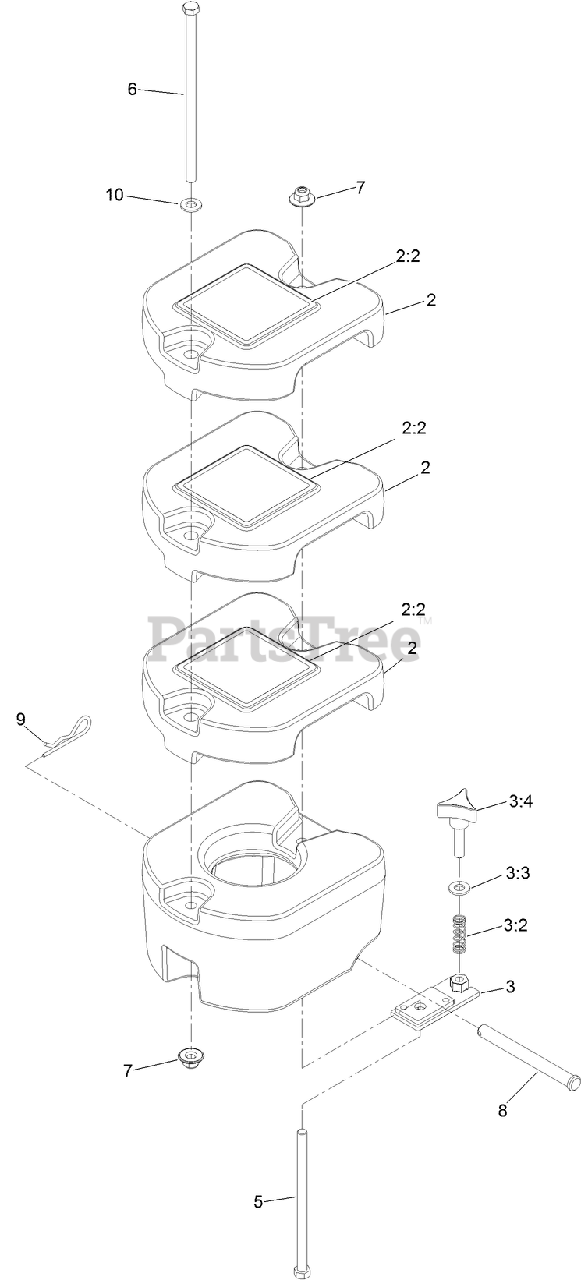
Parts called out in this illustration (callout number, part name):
2	WEIGHT-20LB
2:2	DECAL-WARNING, TRACTION
3	CASTER WEIGHT BRACKET ASM
3:2	Spring
3:3	WASHER-FLAT
5	SCREW-HH
6	SCREW-HH
7	NUT-FLANGE, NI
8	PIN-CLEVIS
9	PIN-COTTER
10	WASHER-FLAT
